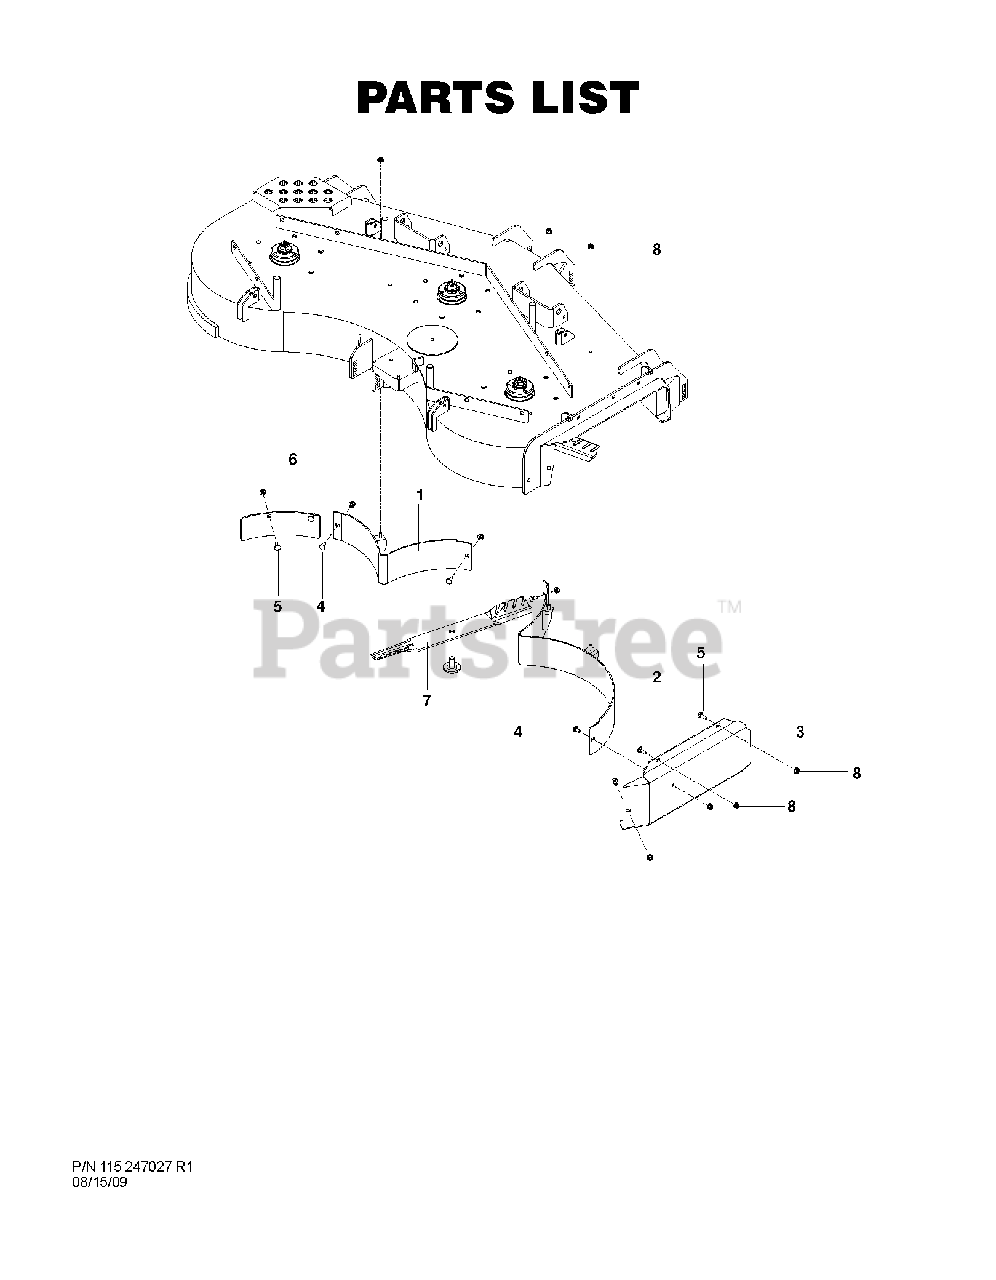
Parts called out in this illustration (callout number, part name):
1	MULCH BAFFLE LH 60" BLACK
2	MULCH BAFFLE RH 60" PTD
3	CAP, MULCH 60" BLACK
4	BOLT 5/16C X 3/4" CARRIAGE
5	RHSNB 5/16C X 1
6	Deck Baffle, 60" LH Corner
7	BLADE, 21" GATOR, 1.25 LIFT
8	5/16-18 NYLOC FLANGE NUT
